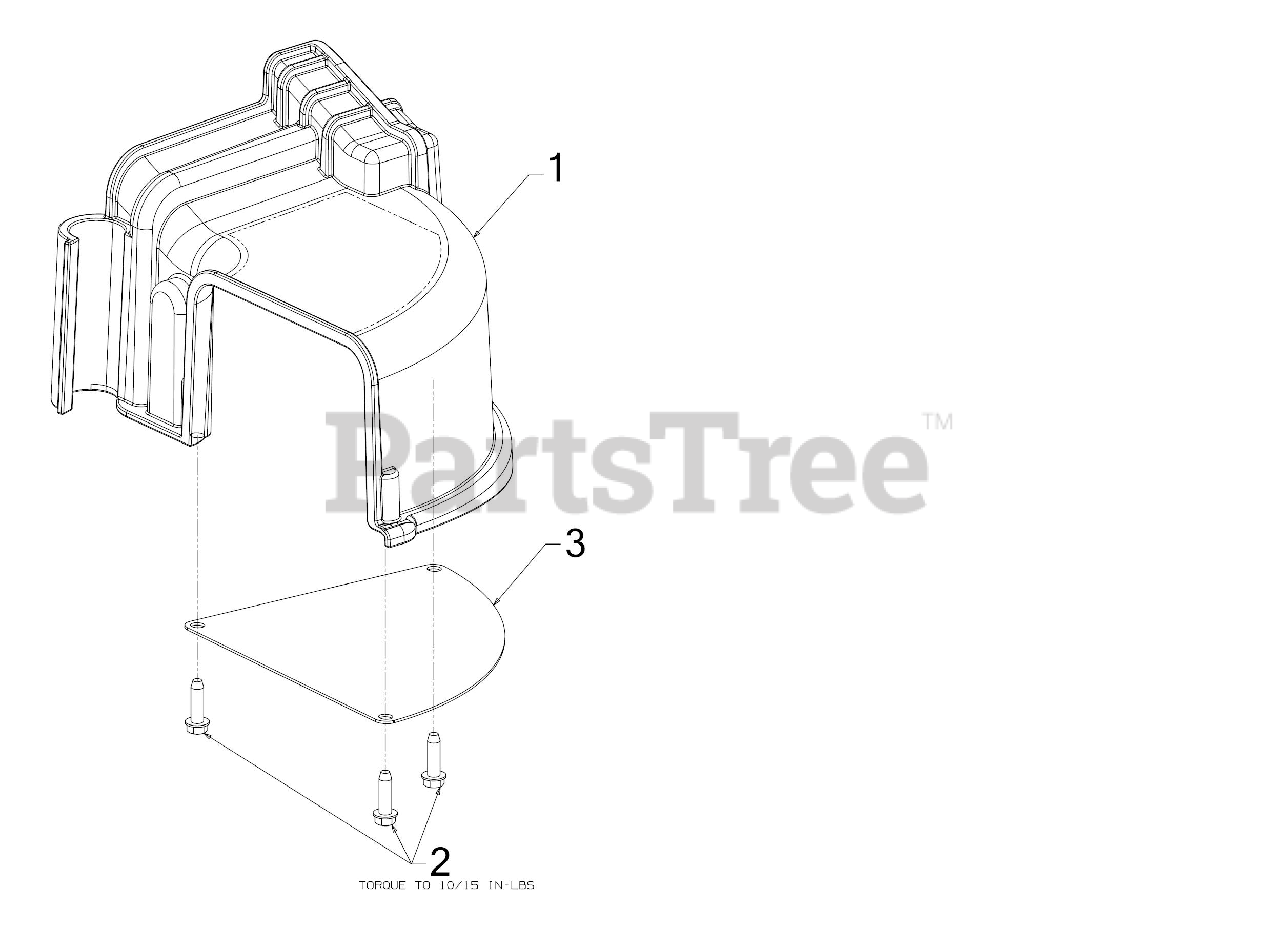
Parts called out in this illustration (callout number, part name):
1	90 DEGREE DISCHARGE CHUTE ASSEMBLY
2	SCREW #12-16 .75
3	DISCHARGE CHUTE BRACKET
